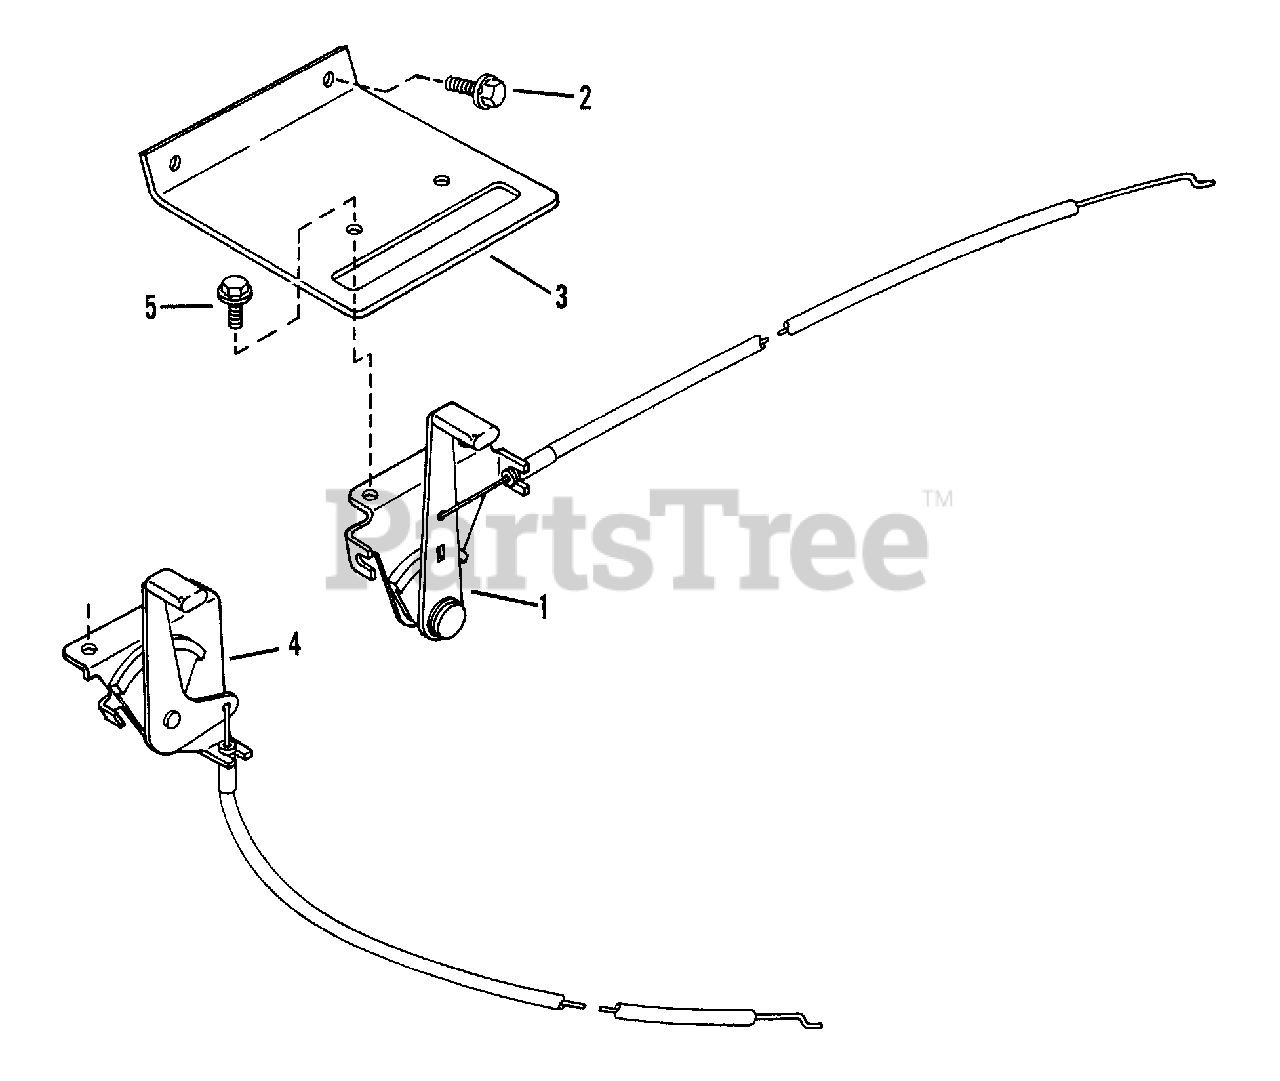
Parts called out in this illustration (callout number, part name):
1	CONTROL, Throttle (Manual Start Tecumseh)
2	SCREW, 1/4-20 x 1/2" Self-Tapping
3	PLATE, Throttle Control
4	CONTROL, Throttle (Electric Start Briggs)
5	SCREW, #10-24 x 1/2" Self-Tapping
